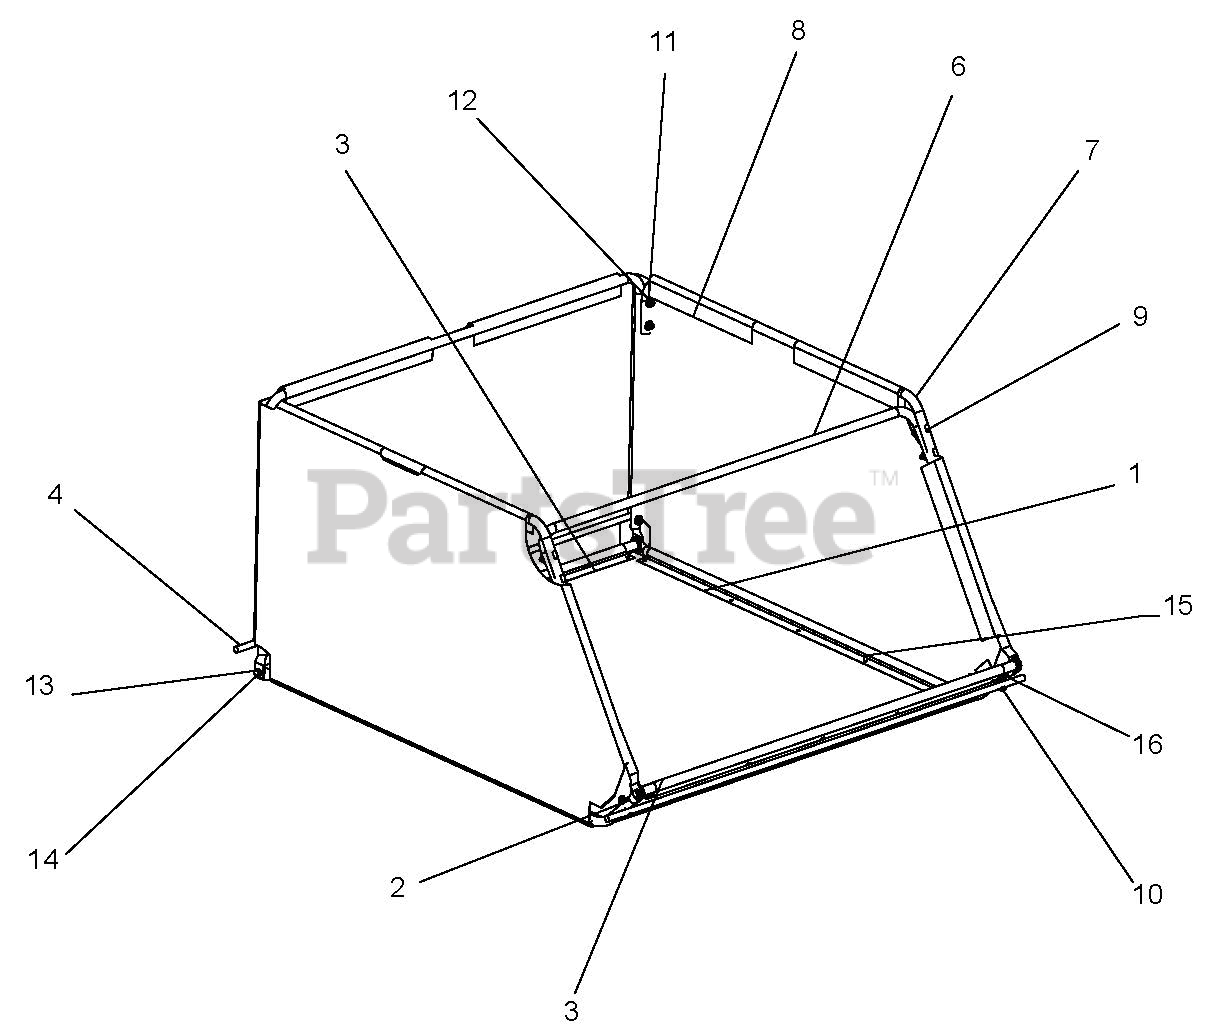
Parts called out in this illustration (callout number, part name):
1	Basket Clamp Assembly
2	Basket Clamp Assembly
3	Basket Clamp Assembly
4	Support Rod
5	Rear Upright
6	Front Upright
7	Frame Basket Side Top
8	Basket Assembly
9	Bolt, 1/4-20 x 2.0 Contour Head
10	Bolt, 1/4-20 x 1.5 Hex 5
11	Washer, 1/4 Flat
12	Nut-Hex, 1/4-20 YWZC
13	Washer, 5/16 Spring Lock
14	Bolt, 5/16-18 x 1.00 Hex 5
15	Rivet, Bulb Tite
16	Basket Bottom
